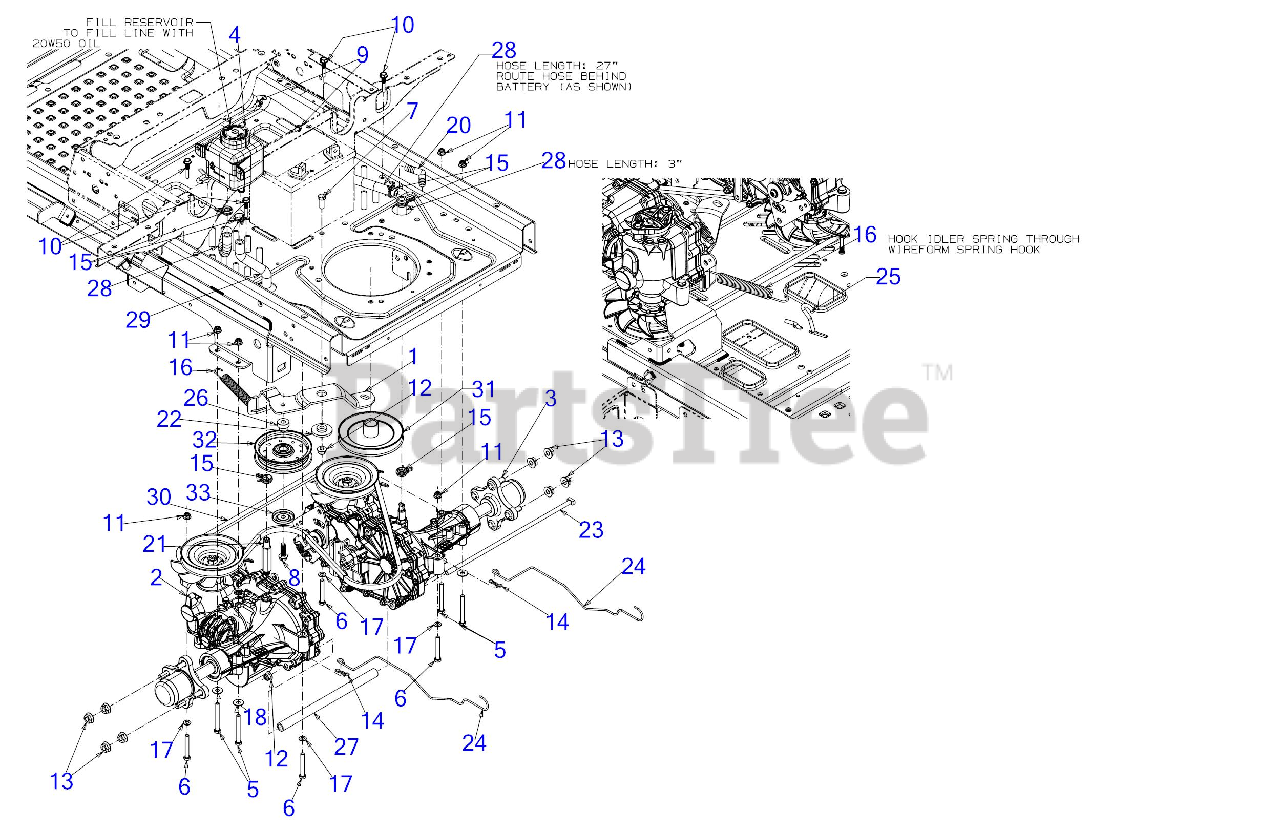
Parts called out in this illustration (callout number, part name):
1	IDLER BRACKET ASSEMBLY
2	HYDRO TRANSMISSION ASSEMBLY (LH)
3	HYDRO TRANSMISSION ASSEMBLY (RH)
4	HYDRAULIC TANK
5	HEX SCREW 5/16-18 x 2.75
6	HEX SCREW 5/16-18 x 2.25 GR5
7	SCREW 3/8-16 x 1 GR5
8	SCREW 3/8-16 X1.250
9	SCREW 1/4-20X.625
10	BELT KEEPER ROD .25 x 1.585
11	FLANGE LOCK NUT 5/16-18
13	HEX FLANGE NUT 7/16-14
14	BOW TIE COTTER PIN 1/4-5/16
15	FUEL HOSE CLAMP
16	EXTENTION SRING .75 DIA. x 6.85
17	FLAT WASHER
18	FLAT WASHER
20	90 DEGREE NYLON FITTING
21	EXTENSION FITTING 9/16-18
22	SHOULDER SPACER
23	SUPPORT TUBE ROD
24	HYDRO BYPASS ROD
25	IDLER SPRING HOOK
26	SHOULDER SPACER
27	TRANSMISSION SPACER .75OD x 11.31
28	FUEL LINE 1/2" ID
29	EXPANSION TANK HOSE
30	TRANSMISSION DRIVE BELT A x 67
30	Cub Cadet TRANS DRIVE BELT A x 67 RZT
30	Troy-Bilt TRANSMISSION DRIVE BELT
31	TRANMISSION DRIVE PULLEY
32	IDLER PULLEY 4.25 DIA
33	IDLER PULLEY CAP
